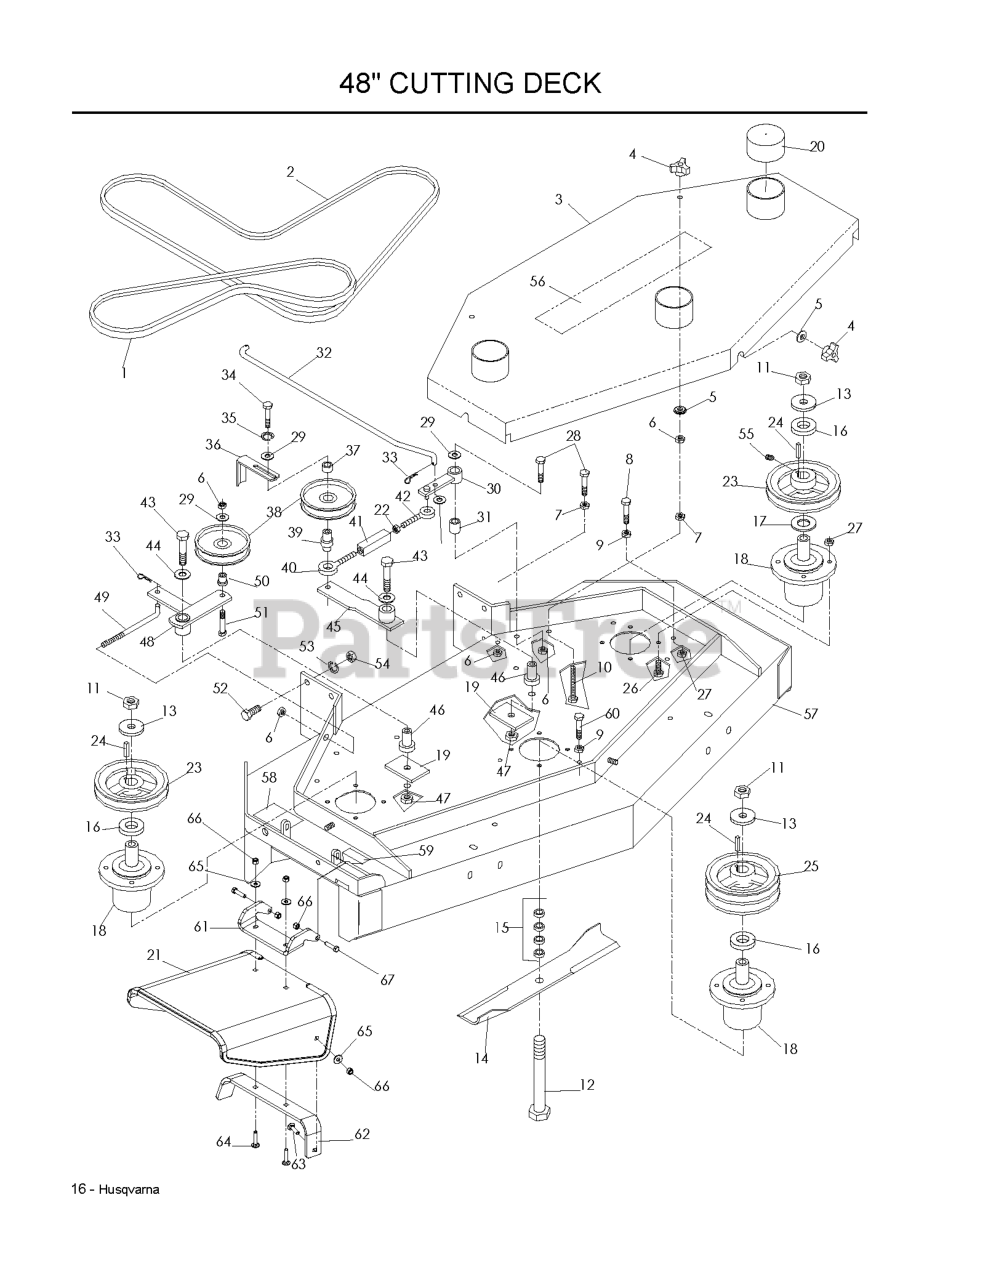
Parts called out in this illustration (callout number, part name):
1	BELT, AUX BLADE
2	BELT - ENG/DECK 48
3	BELT SHIELD 48"
4	KNOB, THREE PRONG
5	WASHER, 3/8 SEALING
6	NUT 3/8C CENTERBLOCK
7	NUT 3/8C WHIZ
8	HCS 5/16 X 3
9	NUT 5/16C WHIZ
10	TAPBOLT 3/8C X 4 1/2
11	NUT 5/8F HEX
12	HCS 5/8-18 X 9 GR5 ZD
12	HCS 5/8F X 8 1/2
13	WASHER, SUPPORT
14	BLADE OEM 16 1/4"
15	BLADE SPACERS
17	MACHINERY BUSHING 10 GA.
18	HOUSING ASM
21	CHUTE, RUBBER DISCHARGE WB
22	NUT 5/16C HEX
23	PULLEY W/SETSCREWS
24	KEY 1/4 SQ X 1 1/8
25	PULLEY, DOUBLE W/SETS
26	HCS 5/16C X 1
27	NUT 5/16C CENTERLOCK
28	HCS 3/8C X 2 1/4
29	WASHER 3/8 FLAT
30	ENGAGEMENT ARM
31	BUSHING, SLEEVE
32	BLADE ROD 48"
33	HAIRPIN #2
34	HCS 3/8C X 2 1/2
35	SLW 3/8 STD
38	IDLER PULLEY
39	EYEBOLT PIVOT
40	EYEBOLT, LH
41	TURNBUCKLE
42	EYEBOLT, RH
43	HCS 1/2C X 2 3/4
44	WASHER 1/2 FLAT
45	ARM WELDMENT
46	IDLER SPINDLE
47	NUT 1/2-13 HEX NYLOC ZD
48	IDLER ARM, AUX.
49	TENSION ROD
50	BUSHING, IDLER FLANGE
51	HCS 3/8-16 X 1 3/4 GR5
52	HCS 7/16C X 1 1/2
53	WASHER 7/16 LOCK
54	NUT 7/16C HEX
55	SET SCREW 5/16 NYLOC
56	DECAL, HUSQ 12" BLUE
57	DECK W/DECALS 48"
58	DECAL, EURO SEVERING
59	DECAL, CPSC
60	HCS 5/16C X 4
61	PIVOT BRACKET - CHUTE
62	BRKT, REINF-CHUTE WB
63	BOLT, CARRIAGE 5/16X1-1/4
64	RHSNB 5/16-18 X 1-1/2 GR 5 ZD
65	WASHER 5/16 FLAT
66	NUT 5/16 NYLOC
67	HCS 5/16C X 1 1/4
